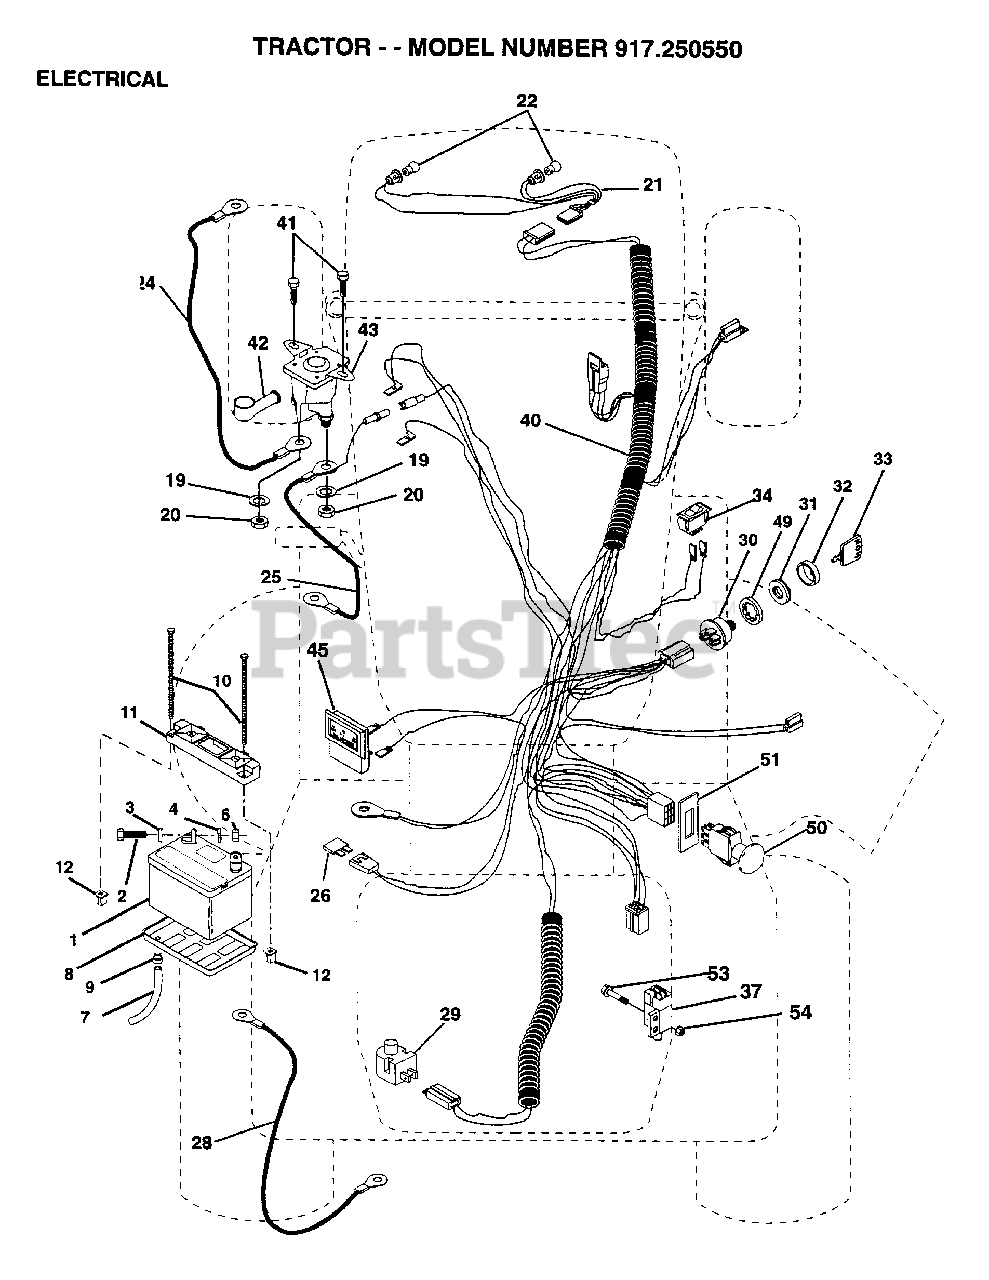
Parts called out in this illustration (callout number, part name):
2	BOLT LT
7	"DRAIN TU T, BATT"
8	"TRAY T, BATTERY"
9	"SCREW, TAPPING LT"
20	NUT
21	"HARNESS,LIGHT SOC"
22	HEADLAMP BULB
23	LOCKWASHER
24	CABLE.BATY.22.RED
25	CABLE.BATRY.4GA.
26	FUSE HYT
28	CABLE.BATRY.4GA.
29	SWITCH SEAT
32	COVER KEY SWITCH
33	KEY MLD CRAF DELT
34	SWITCH LT
37	SWITCH INTERLOCKT
40	HARNESS.IGN.95.GT
41	SCREW
45	AMMETER
49	LOCKWASHER
51	RING RETAIN PTO
53	SCREW
54	"NUT,KEPS"
